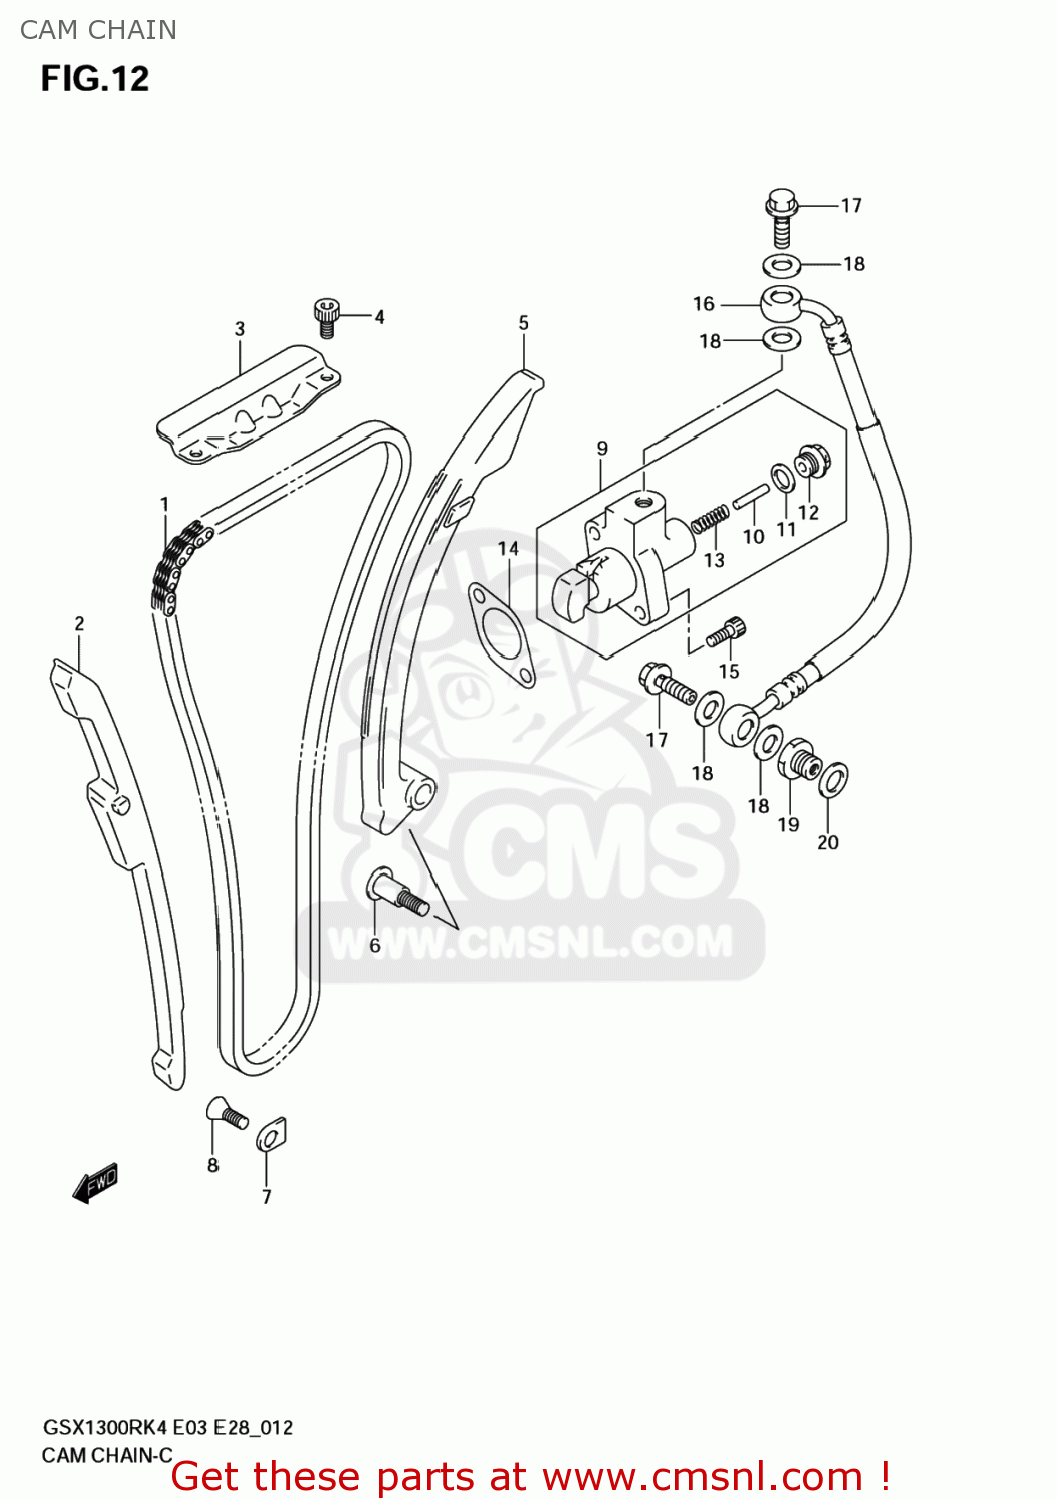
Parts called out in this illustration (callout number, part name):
1	CHAIN COMP,CAMSHAFT DRIVE
2	GUIDE,CAM CHAIN NO.1
3	GUIDE,CAM CHAIN NO.2
4	BOLT,STRANGER
5	TENSIONER,CHAI
6	BOLT,CAM CHAIN TENSIONER/GUIDE
7	RETAINER,CAM CHAIN GUIDE NO.1
8	SCREW
9	ADJUSTER SET,T
10	SHAFT,ADJUSTER
11	GASKET,TENSIONER ADJUSTER (NAS)
12	PLUG,FR TENSIONER ADJ
13	SPRING,MAIN
14	GASKET,TENSIONER ADJUSTER (NAS)
15	BOLT,CL.COVER
16	HOSE,CAM CHAIN TNSN ADJ OIL
17	BOLT,ADJ OIL HOSE UNION
18	GASKET(8.2X14X1) (NAS)
19	PLUG,ADJ OIL HOSE UNION
20	GASKET(13.8X18.8X4.8) (NAS)
